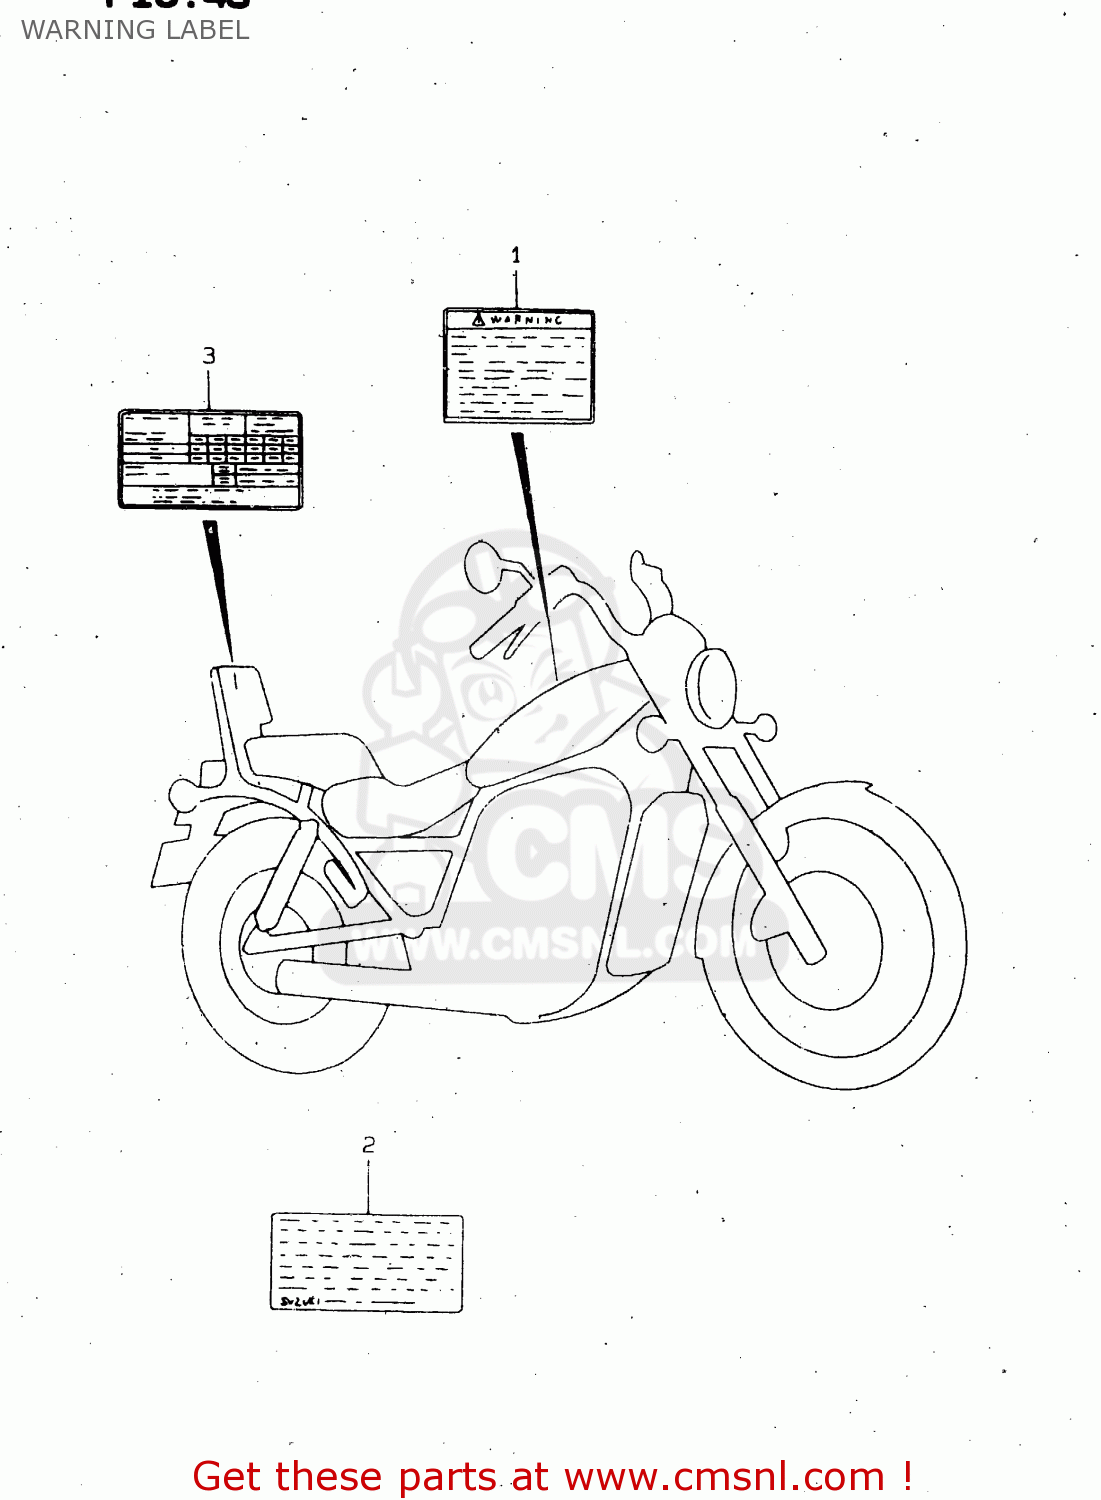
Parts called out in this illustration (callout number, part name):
1	LABEL,WARNING
2	LABEL,CAUTION
3	LABEL,TIRE INFORMATION
4	O.M.VS1400GLP
